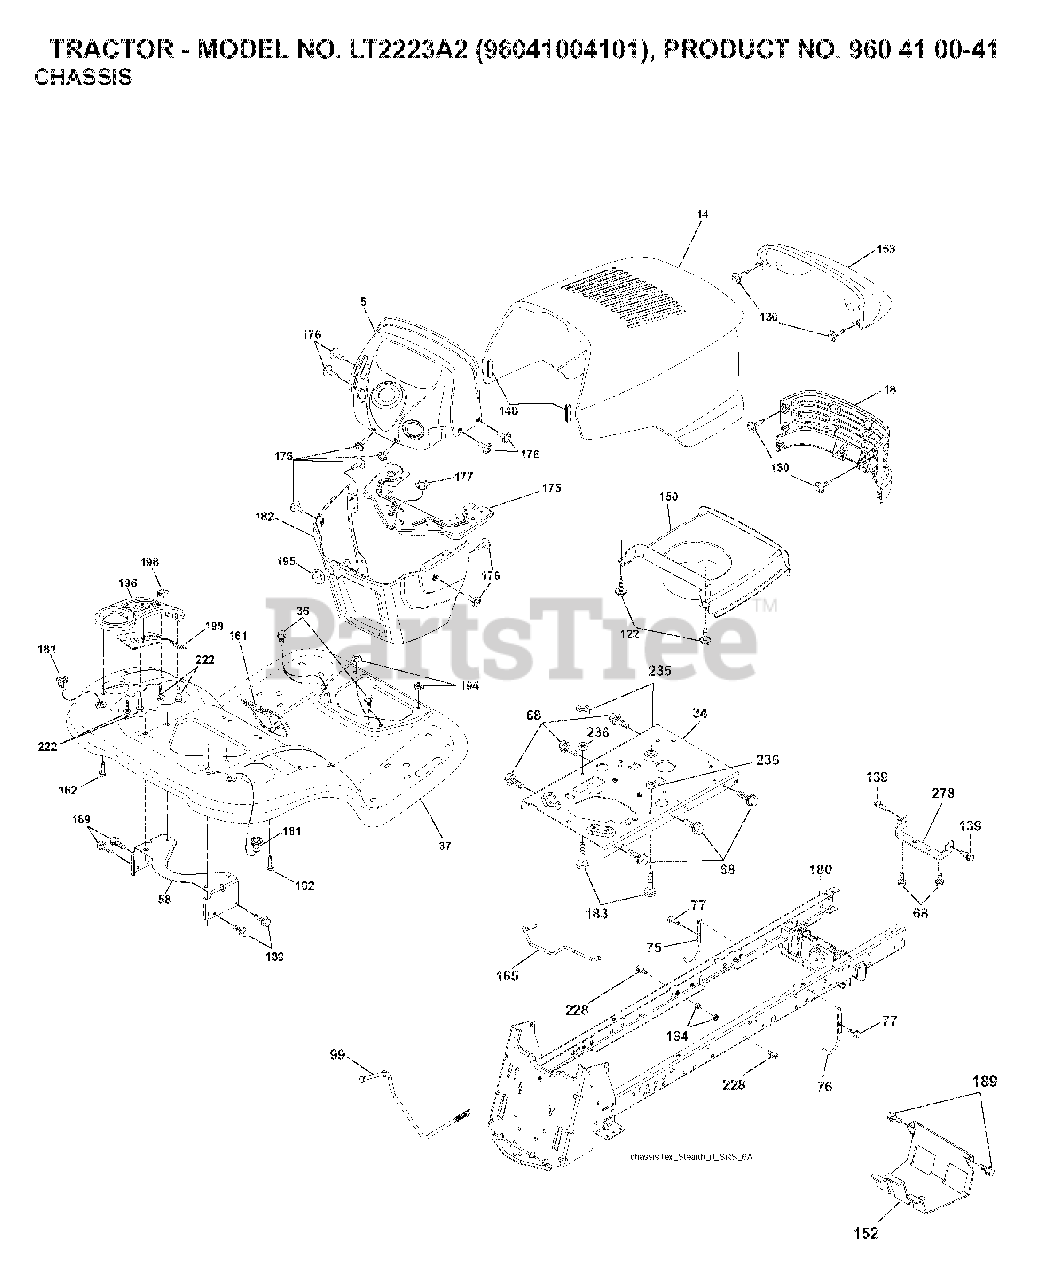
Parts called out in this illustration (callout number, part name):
5	DASH.UPR.STEALTH
34	PLATE.ENGINE.WELDED.CHASSIS
36	SCREW 5/16"
58	BRKT.SUPPORT.FNDR/TANK
68	SCREW LT
75	ROD UPSTOP
76	ROD UPSTOP
77	SCREW 3/8-16X1
99	ROD.BYPASS.HYDRO.0510/0610.GT
122	SCREW.WSHD.HEX10-32X5/8
130	SCREW
139	BOLT, SHOULDER 5/16-18
148	EXTRUSION BUMPER
150	DUCT HOOD
152	SHIELD BROWNING
161	CONSOLE.FUEL.WINDOW.STGT.BLACK
162	SCREW.HI-LO.CONSOLE
165	SUPPORT.TANK.REAR.W/TE
175	CROSSMEMBER.
176	SCREW.#10-24X5/8.RN.QU
177	BUSHING,STEERING
180	CHASSIS.GT.SLOPED.DRAWBAR.
181	FEND/FTRST.PCH.CPH.NFW
182	DASH.LOWER.
183	BOLT.5/16-18X1-1/4 FULL.THREAD
189	SCREW
194	NUT LOCK HEX FLANGE 5/16-18
195	PLUG.HOLE.DASH.LOWER.12V.BLK
198	INDICATOR DECK LIFT
199	PLATE DECK LIFT
222	SCREW.1/4-20X5/8
228	STUD.FASTNER.W/ANTI-ROTATE
235	SPACER FENDER
236	NUT.CENTERLOCK.5/16-
278	BRKT.HOOD/MUFF.STEALTH
